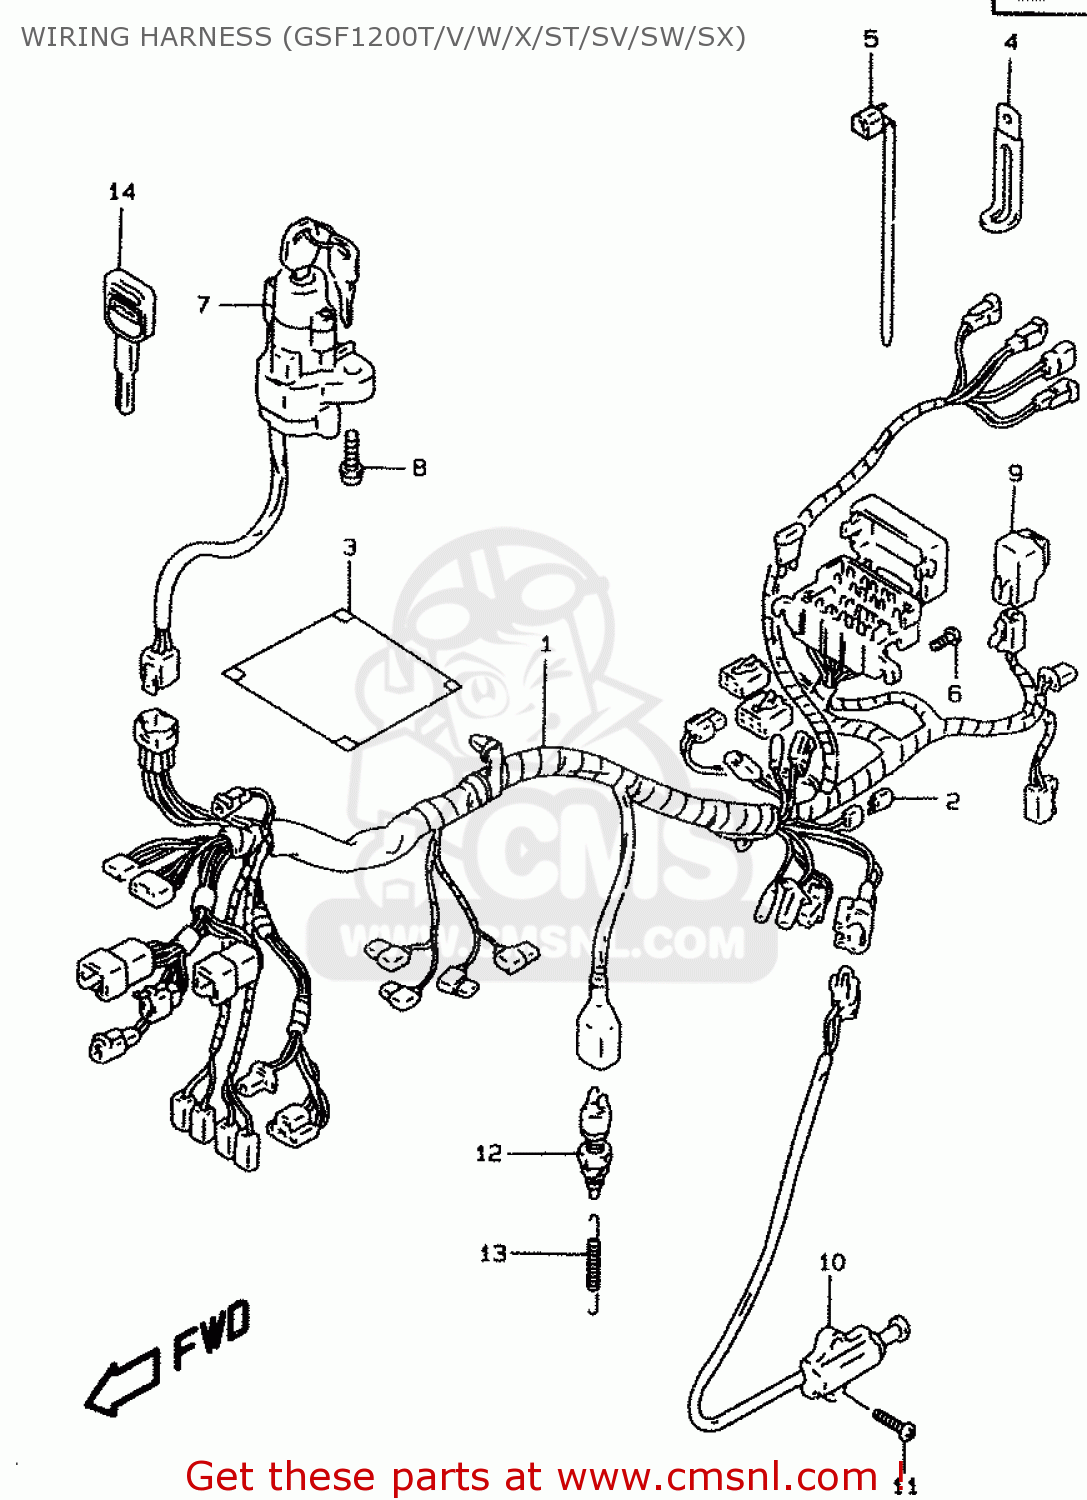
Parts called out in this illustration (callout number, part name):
1	HARNESS,WIRING
2	DIODE(STANLEY DE8804)
3	COVER,WIRING HARNESS
4	CLAMP(L:65)
5	CLAMP(L:125)
6	SCREW 6X12
7	LOCK ASSY,STEERING
8	BOLT(8X20)
9	RELAY ASSY
10	SWITCH ASSY,SIDE STAND
11	SCREW
12	SWITCH ASSY,STOP LAMP
13	SPRING
14	KEY,BLANK
